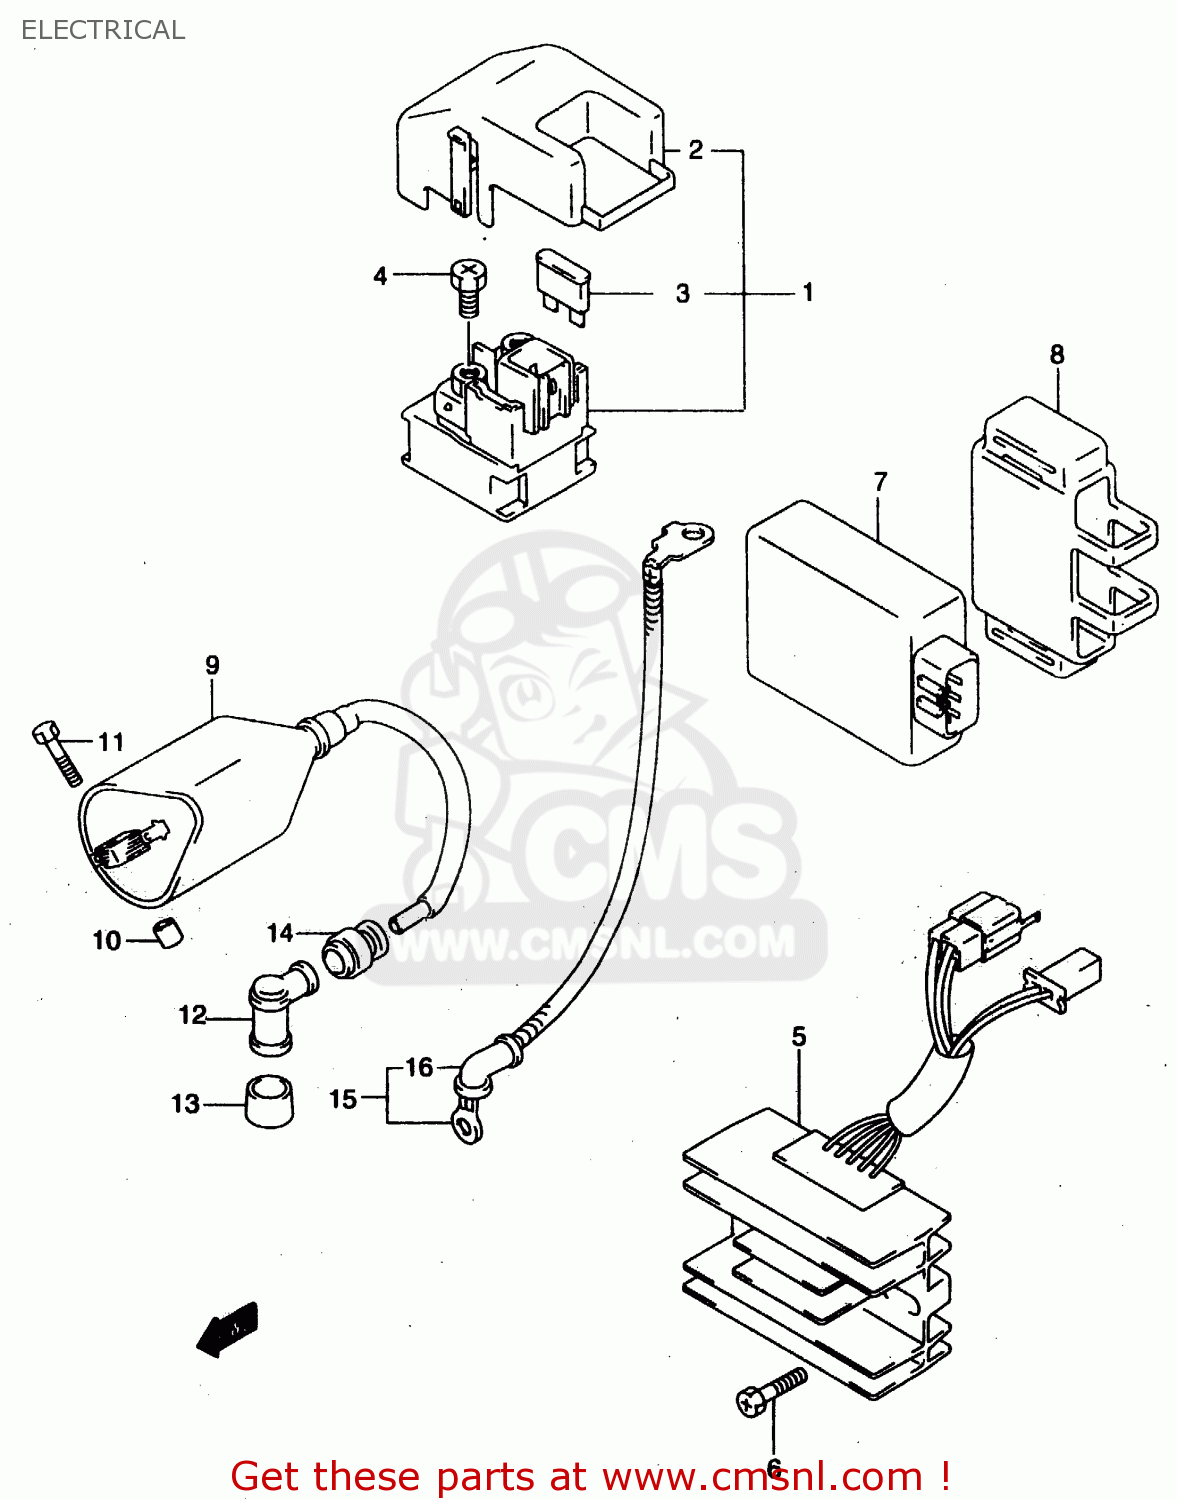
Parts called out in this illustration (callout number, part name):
1	RELAY ASSY,STARTING MOTOR
2	COVER
3	FUSE(20A)
4	SCREW(6X8)
5	RECTIFIER ASSY
6	BOLT(6X20)
7	IGNITOR ASSY
8	CUSHION,CDI UNIT
9	COIL ASSY,IGNITION
10	SPACER(6X12X10)
11	BOLT, IGNITION
12	CAP ASSY,SPARK PLUG
13	SEAL,SPARK PLUG CAP
14	SEAL,HIGH TENSION CORD
15	WIRE,STARTER MOTOR LEAD
16	CAP,STARTER MOTOR LEAD
